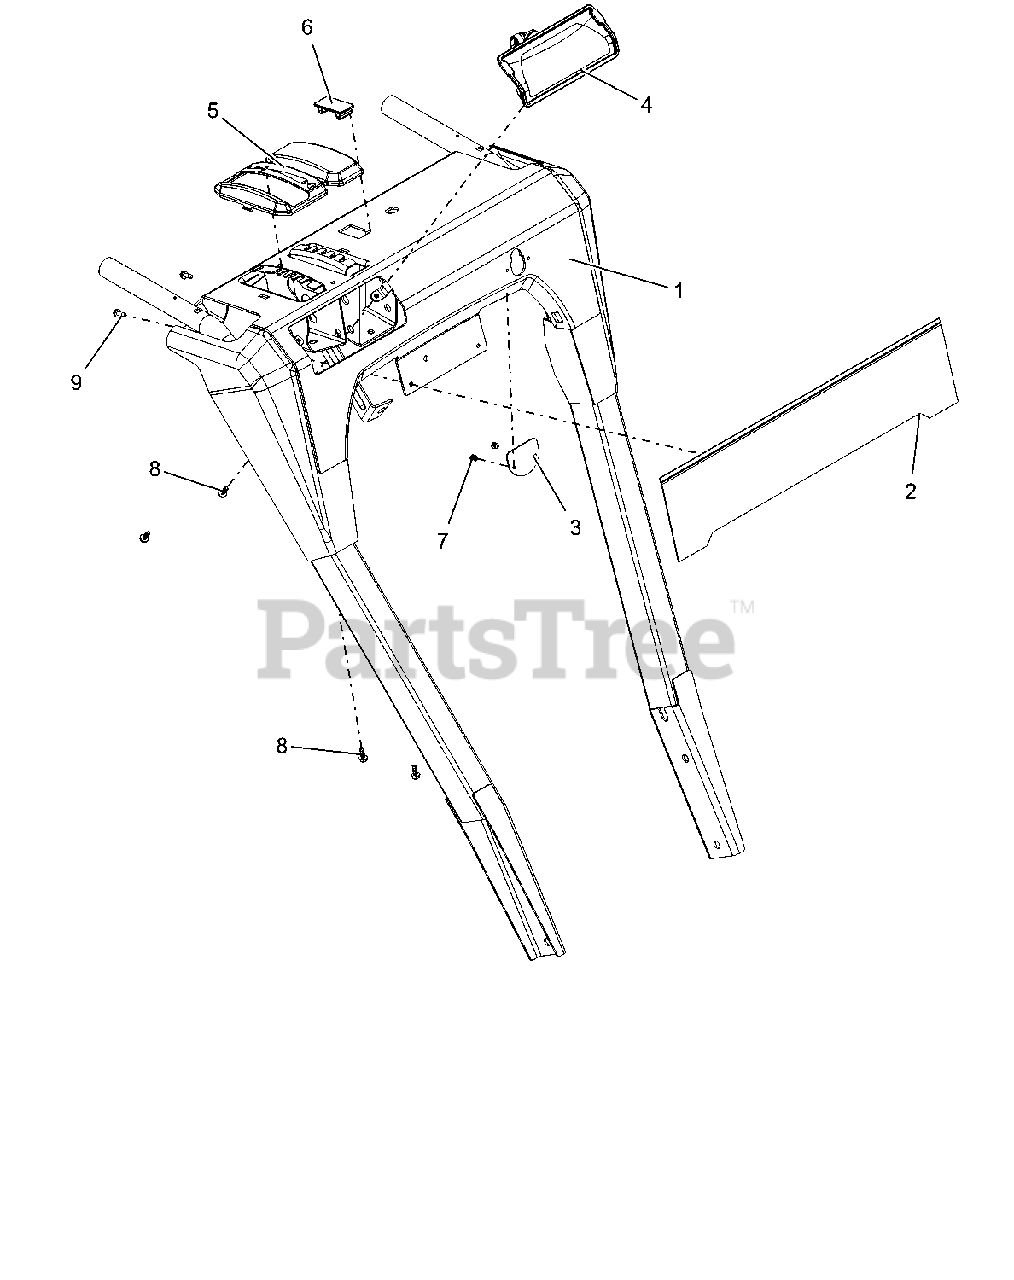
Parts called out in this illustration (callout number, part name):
1	PANEL, DASH - W/CTR DECAL
2	WLDMT, BRAND PLATE
3	COVER, DASH BRKT, BRUSH
4	HEADLIGHT ASY, HOLO 15W 2 SHOT
5	BEZEL, SHIFT - FRICTION BRUSH
6	PLUG,DASH PANEL
7	RVT-POP #43 .125X.313 STL ZINC
8	SCR-TAP #10X.50 BOSS INDHXHD
9	SCR-TAP 10-24X.50 HWH TR YWZC
